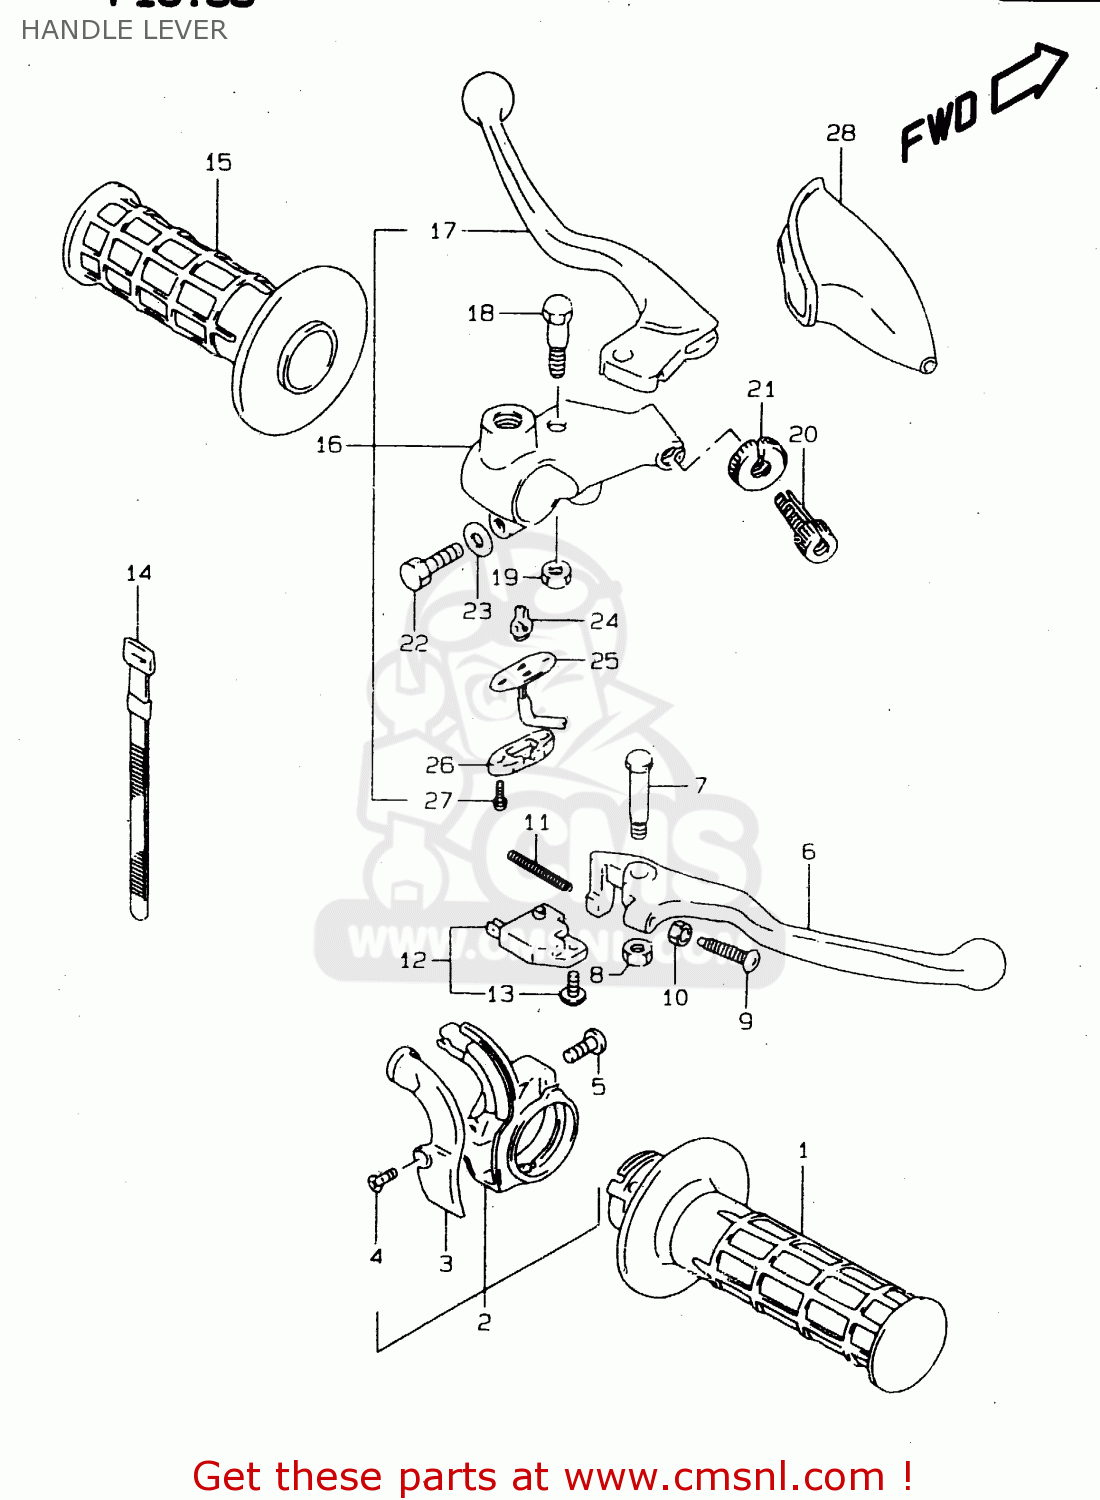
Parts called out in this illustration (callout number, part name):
1	GRIP,THROTTLE
2	CASE ASSEMBLY,THROTTLE
3	COVER,THROTTLE CASE
4	SCREW,UPPER
5	SCREW
6	LEVER,BRAKE
7	BOLT,BRAKE LEVER
8	NUT 6MM
9	BOLT,ADJUST
10	NUT
11	SPRING,RETURN
12	SWITCH ASSEMBLY,STOP
13	SCREW
14	CLAMP(L:120)
15	GRIP,L
16	LEVER ASSY,CLUTCH
17	LEVER,CLUTCH
18	BOLT,LEVER PIVOT
19	NUT 6MM
20	ADJUSTER,CABLE
21	NUT,LOCK
22	BOLT
23	WASHER
24	CONTACT,SWITCH
25	HARNESS ASSY,WIRE
26	COVER,FR BK TERMINAL BASE
27	SCREW
28	COVER,CLUTCH LEVER
